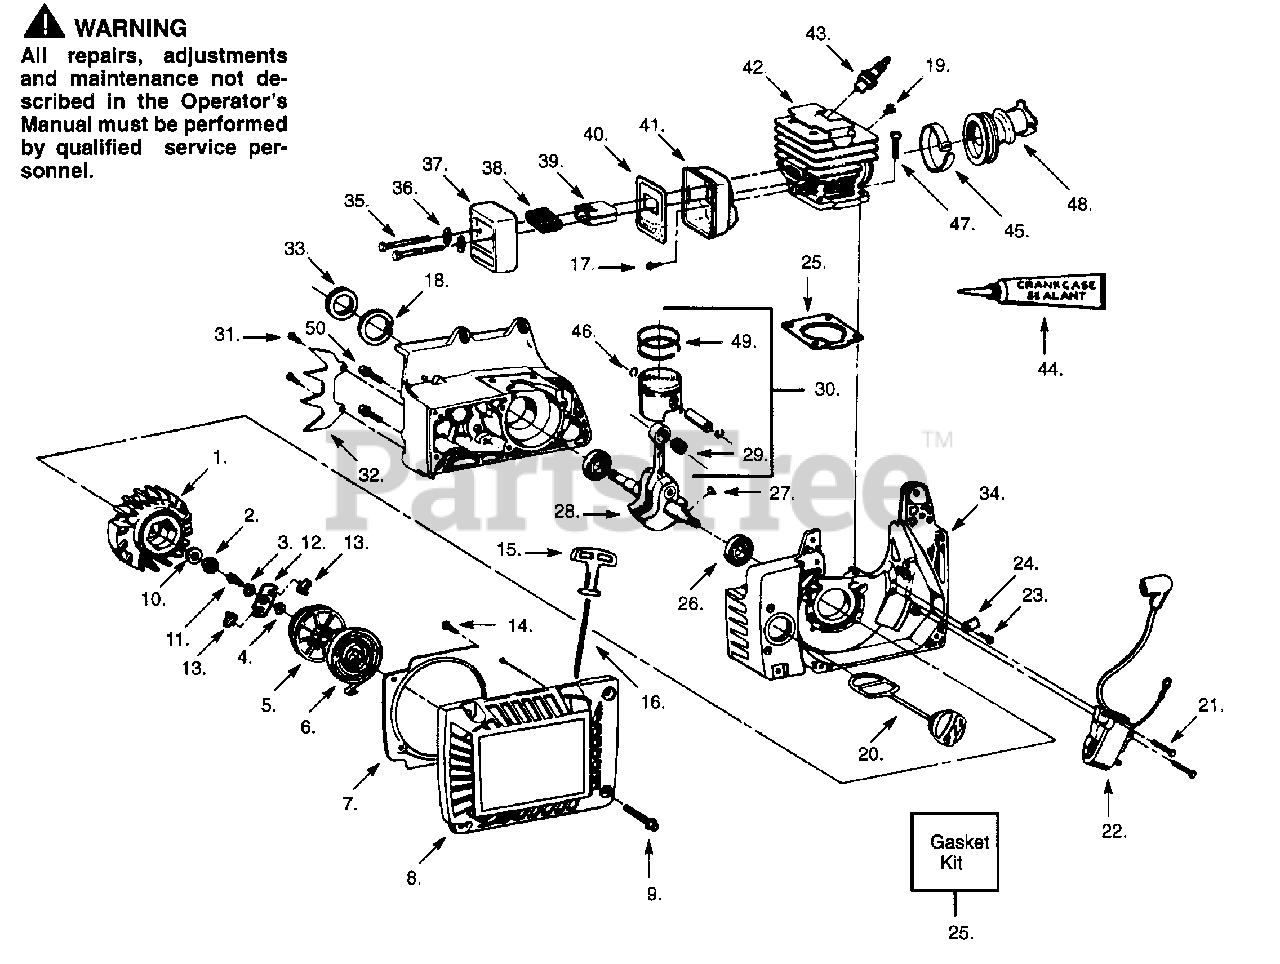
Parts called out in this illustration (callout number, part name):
1	Flywheel
3	Wave Washer
4	Retainer
5	Starter Pulley
6	Starter Spring
7	Baffle Plate
8	Fan Housing
9	Screw
12	Starter Cam
13	Starter Dog
15	Starter Handle
16	Rope Kit
18	Snap Ring
20	Oil Cap Ass'y. (Incl. O Ring)
21	Screw
22	Ignition Module
25	Model 336C
25	Model 365C
26	Crankshaft Bearing
27	Flywheel Key
28	Crankshaft/Rod Ass'y.
29	Piston Pin Bearing
30	Model 336C
30	Model 365C
33	Crankshaft Seal
34	Crankcase Ass'y.
34	Model 336C
34	Model 365C
37	Model 336C
37	Model 365C
38	Model 336C
38	Model 365C
39	Model 336C
39	Model 365C
40	Model 336C
40	Model 365C
41	Model 336C
41	Model 365C
42	Model 336C
42	Model 365C
43	Model 336C
43	Model 365C
45	Clamp Ass'y.
46	Retainer
48	Carb. Adapter
49	Model 336C
49	Model 365C
